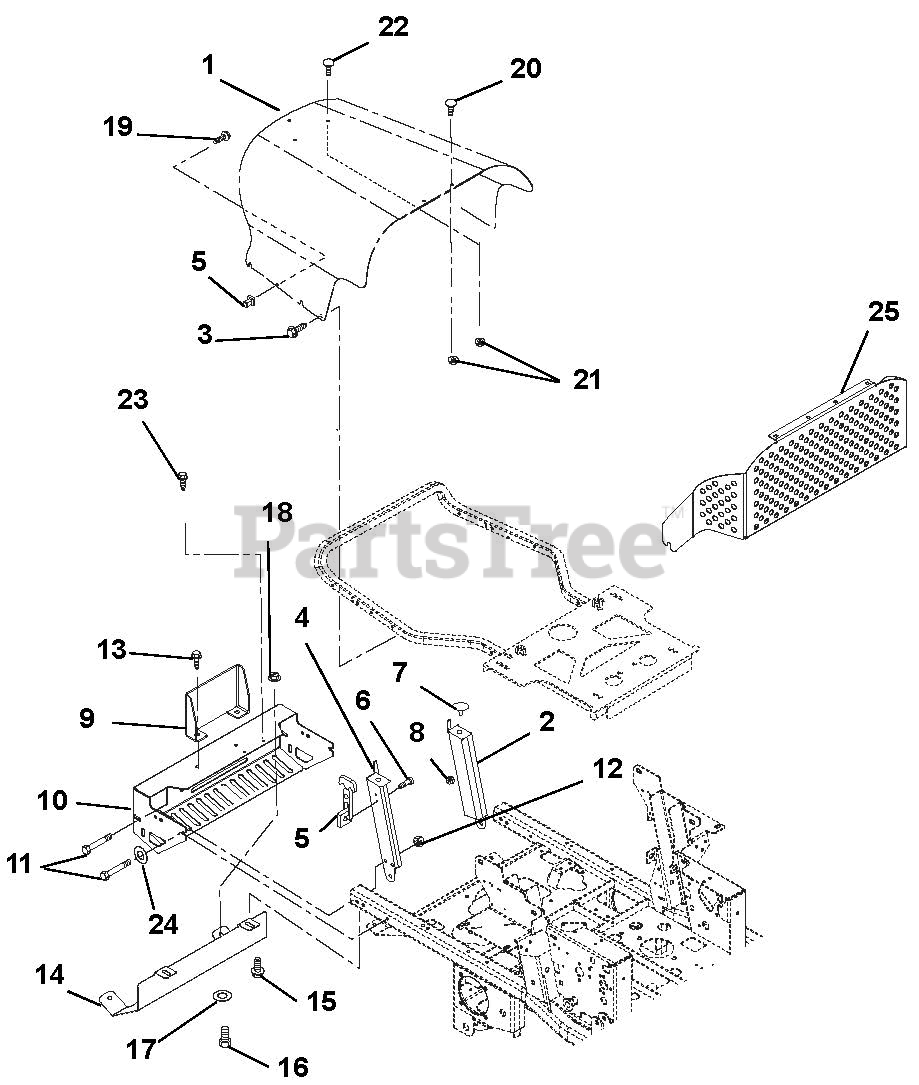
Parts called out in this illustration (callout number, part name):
2	Weldment, Hood Support, Left Hand
3	Screw, Tapping Hex Washer Head .38-16 x .75
4	Weldment, Hood Support Right Hand
5	Latch, Rubber
6	Screw, Machine Hex Washer Head 10-24 x .50
7	Button Bumper
8	Nut, Spin Lock Flange .312-18
9	Guard, Muffler
10	Bumper, Rear
11	Bolt, Hex .38-16 x 2.75 Grade 5
12	Nut, Locking Top Flange .38-16
13	Screw, Tapping Hex Washer Head .38-16 x .75
14	Heat Shield
15	Screw, Tapping Hex Washer Head .38-16 x .50 Thread Rolling YWZ
16	Bolt, Hex .38-16 x .75 Grade 5
17	Washer, Flat Steel .438 x1.00 x .083 YWZ
18	Nut, Locking Top Flange .38-16
19	Screw, Machine Hex Washer Head 10-24 x 1.50
20	Bolt, Round Head Square Neck .25-20 x .50 Grade 5
21	Nut, Locking Top Flange .25-20
22	Bolt, Round Head Square Neck .25-20 x .75 Grade 5
23	Screw, Tapping Hex Washer Head Thread .25-20 x .50
24	Washer, Flat Steel .406 x .812 x .065
25	Plenum, Hood
